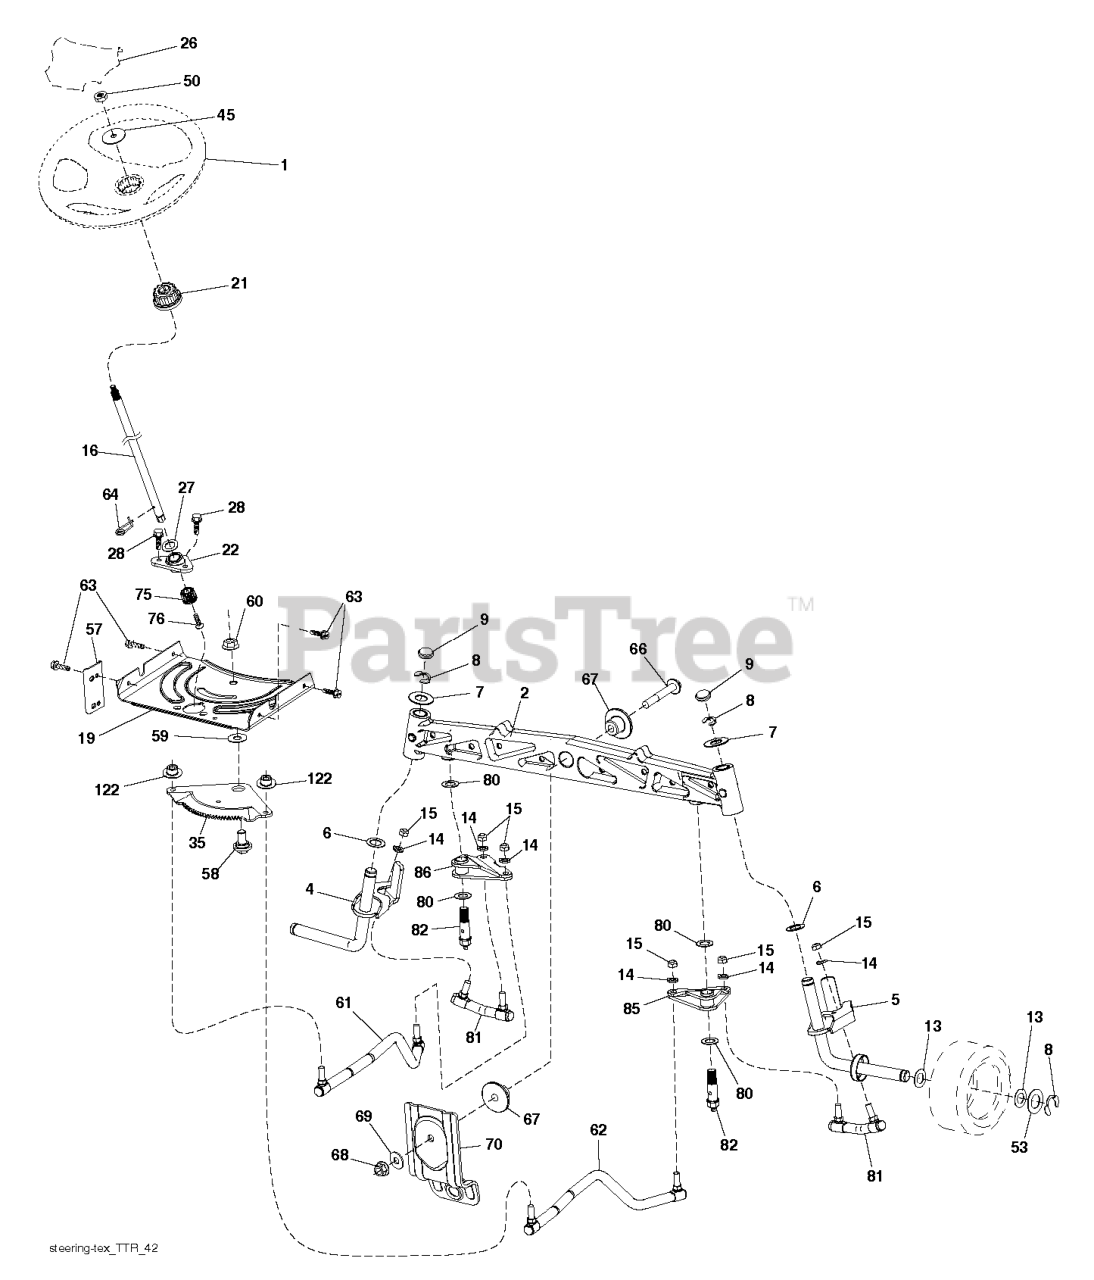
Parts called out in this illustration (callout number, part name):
1	WHEEL.STEER.HUSQ.SR.498.OVMLD
2	RP SUBASM.AXLE.CAST.NZTR.
4	SPINDLE WELDMENT.SPINDLE.LH.15
5	SPINDLE WELDMENT.SPINDLE.RH.15
6	THRUST WASHER
9	CAP.SPINDLE.BLACK
14	WASHER, LOCK 3/8
15	NUT CROWNLOCK 3/8-24
16	SHAFT.STEER.2HIGH.SPLND.PLATED
19	PLATE.STEER.DDL.NLT/NG
21	ADAPTER.WHEEL.STEER.SPLND.ALUM
22	BEARING.SUBASM.SHAFT.STEER.LOW
26	INSERT.CAP.WHL.STRG.HUSQ.PREM
27	WASHER LT
28	SCREW, 3/8-16X3/4
35	GEAR GEAR.SECTOR.TEX.NZTR
45	WASHER.3/8ID.2-3/8OD.12GA.PLTD
50	NUT LOCK FLG 3/8-16 UNC
53	WASHER.HARDENED
57	BRKT.UPSTOP.GT/LT.TEX
58	BOLT.SHOULDER.SECTOR.P
59	WASHER.THURST.SECTOR.S
60	NUT FLANGE LOCK 5/8-11
61	LINK SUBASM.LINK.DRAG.LH.NZTR
62	TUBE TUBE
63	SCREW
64	RETAINER.CLIP.SPRING.S
66	BOLT HEX FGHD 7/16-14 X 3 SERR
67	BUSHING.PM.FRONT AXLE
68	NUT.LOCK.FLANGE.7/16
69	WASHER.1.5X.505X.118
70	BRACKET.FRT.DECK.SUSP.RR.MT431
75	PINION.ZINC PLATED
76	SCREW HEAD SOCKET LRVB
80	THRUST WASHER
81	LINK SUBASM.LINK.CROSS.NZTR
82	SUBASM;PIVOT;BOLT;NZTR
85	PIVOT SUBASM.PIVOT.RH.NZTR
86	PIVOT SUBASM.PIVOT.LH.NZTR
122	CAP.GEAR.SECTOR.TEX
